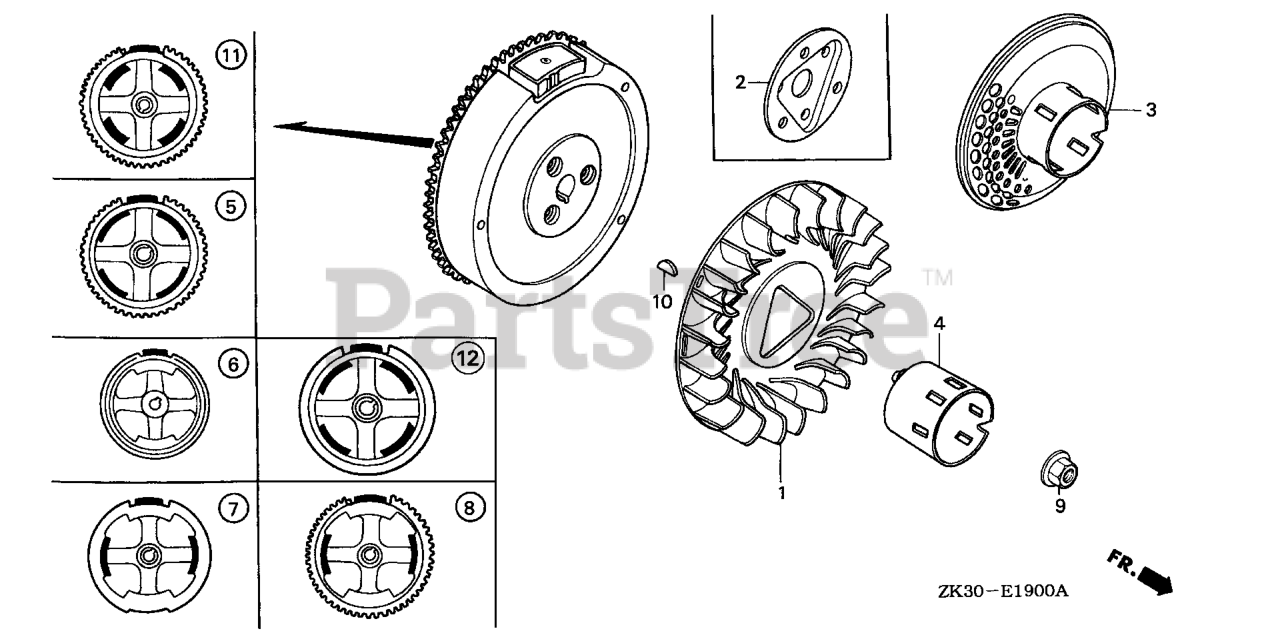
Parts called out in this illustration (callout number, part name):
1	FAN, COOLING
3	PULLEY, STARTER (SCREEN GRID)
5	FLYWHEEL (4 POLE)
9	NUT, SPECIAL (16MM) (1)
9	NUT, SPECIAL (16MM)
10	KEY, SPECIAL WOODRUFF (25X18)
